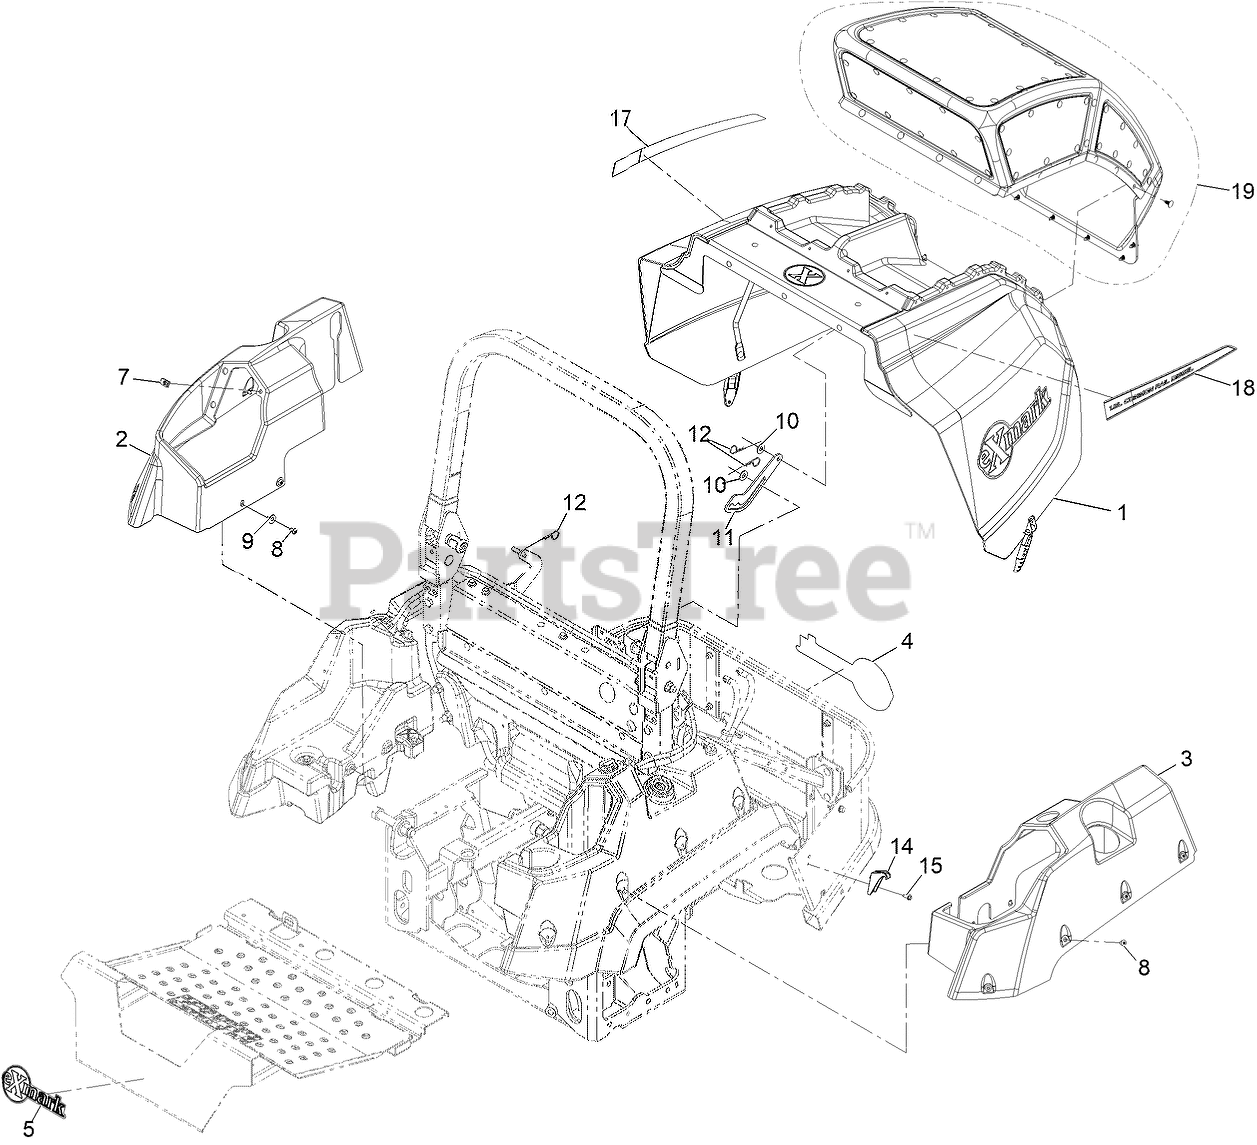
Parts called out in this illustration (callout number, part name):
1	ASM, HOOD LZSD
2	COVER-TANK, RH
3	COVER-TANK, LH
4	DECAL-EXMARK
5	DECAL-EXMARK
8	SCREW-TORX
9	WASHER-FLAT
10	WASHER-FLAT
11	PROP-HOOD
12	PIN-COTTER, HAIR
14	LATCH-CATCH
15	SCREW-HWH
17	DECAL-COMMON RAIL DIESEL-RH
18	DECAL-COMMON RAIL DIESEL-LH
19	ASM, HOOD-INTAKE
